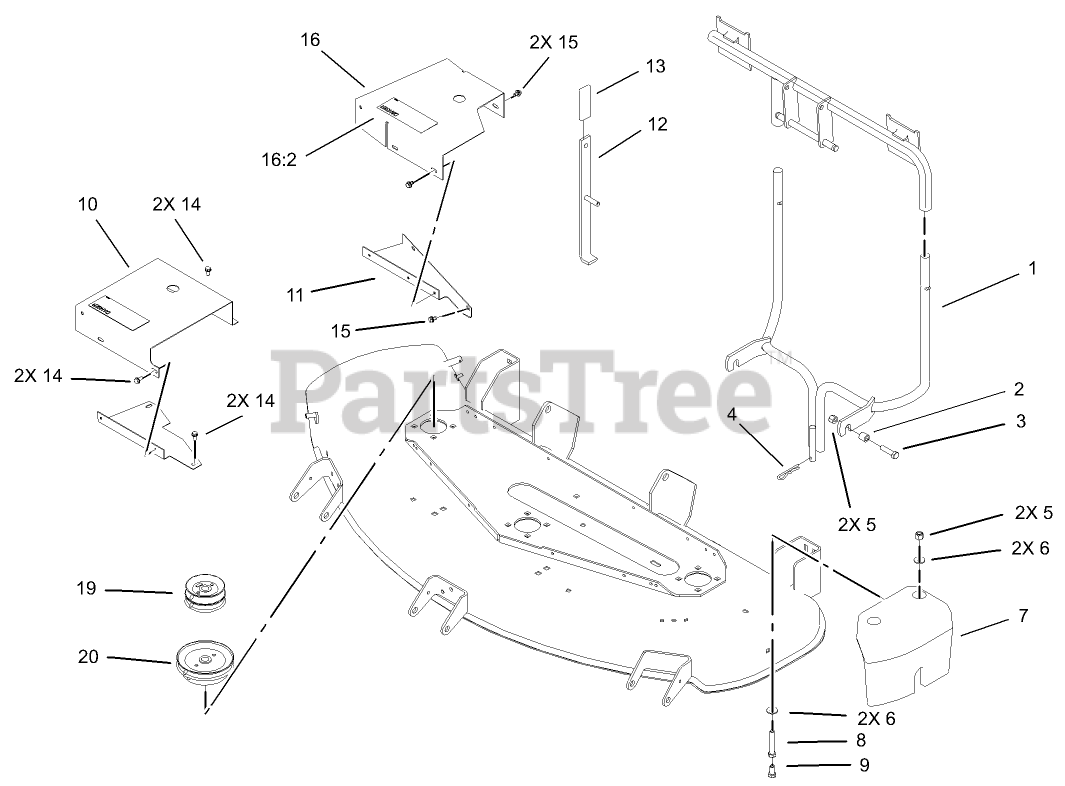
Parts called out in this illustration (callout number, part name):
1	BRACKET-BAGGER
2	SPACER
3	SCREW-HH
4	PIN-COTTER, HAIR
5	NUT-LOCK, NI
6	WASHER-FLAT
7	WEIGHT
8	SCREW-HH
9	SCREW-HH
10	SHIELD ASM
11	ADAPTER-SHIELD
12	HOV LEVER ASM
14	SCREW-HWH
15	SCREW-HHF
16	SHIELD ASM
16:2	DECAL-DANGER
19	PULLEY
20	PULLEY
